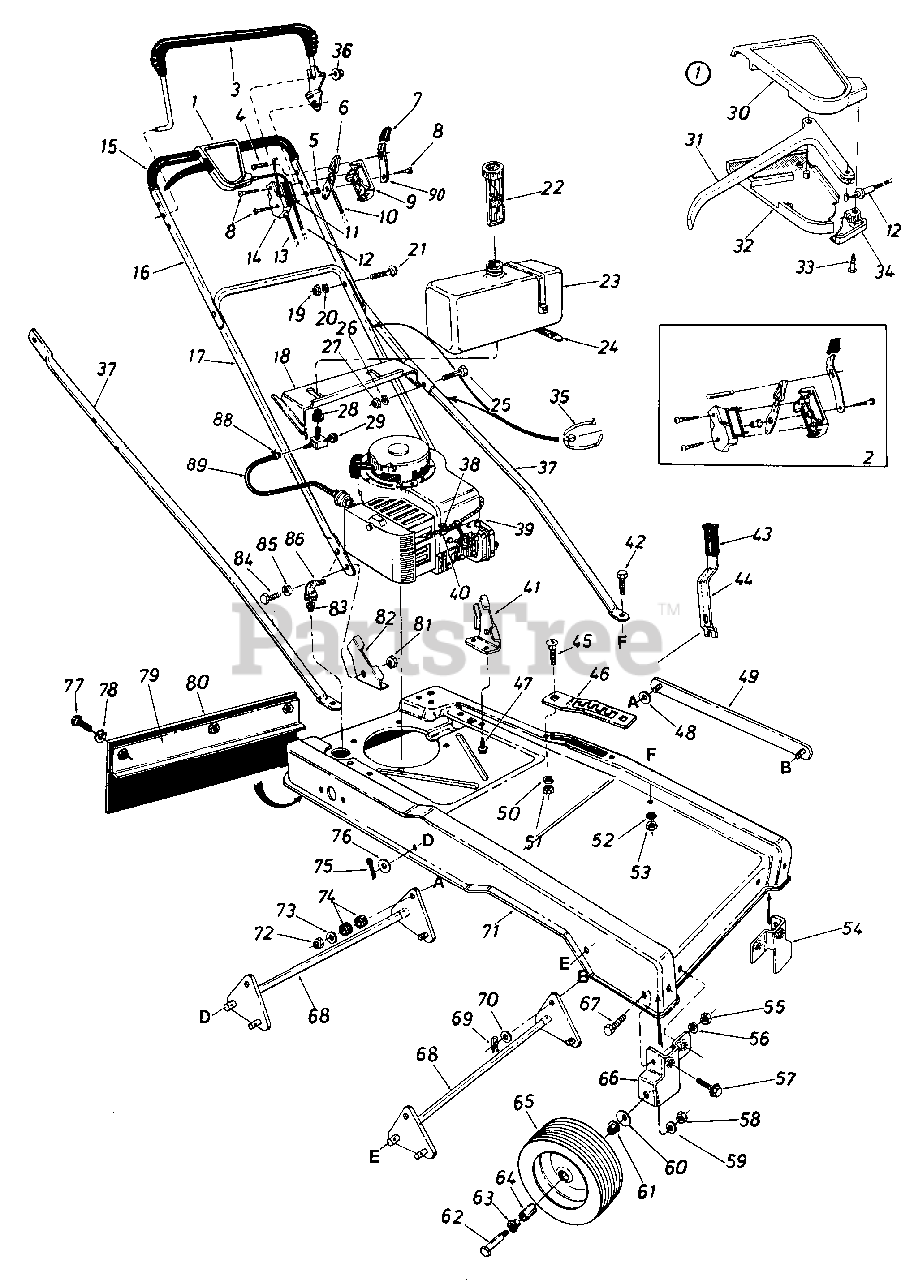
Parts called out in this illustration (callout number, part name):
1	WASHER-FL .322 ID x 1.25 x .060
2	KIT-THROTTLE CONTROL
4	PIN-LOCKING
5	PIN-CONTROL DISC
6	LEVER-THROTTLE CONT-REV
7	KNOB
8	SCREW-TRUSS MACH
9	PANEL HALF-CONTROL
10	WIRE-CONTROL
11	LABEL
12	CABLE-CLUTCH x 50.0
13	CABLE-CLUTCH
14	PANEL HALF-CLUTCH
15	GRIP-SHRINK-25 IN
16	HANDLE-UPPER
17	HANDLE-LOWER PAINTED
18	BRACKET-GAS TANK MTG
19	NUT-HEX 5/16-18
20	WASHER-LOCK-5/16
21	BOLT-CARRIAGE 5/16-18 x 1.50
22	GAUGE-GAS
24	TIE-CABLE
25	SCREW-HEX 5/16-24 x 1.25
26	WASHER-FL-.344ID x .75OD x .250 SP
26	WASHER-LOCK-5/16
27	NUT-5/16-24
28	BUSHING
29	VALVE-SHUT OFF
30	COVER-HALF-CONTROL
31	LEVER-CONTROL
32	COVER-HALF CONT-LWR
33	SCREW-FL C-SUNK AB
34	CAP-CABLE MTG
35	TIE-CABLE
37	STRUT-43.44 IN LG
38	SCREW-HEX WASH HD TAP
40	CLAMP-CASING
41	BRACKET-HANDLE MTG
42	SCREW-HEX 5/16-18 x .75
43	GRIP-FL BAR-END
44	HANDLE-LIFT
45	BOLT-CARRIAGE 5/16-18 x .62
46	BRACKET-SUPPORT
47	SCREW-HEX WASH HD 5/16-18X1/2
48	WASHER-FL-.406ID 1.25OD X.157/.172
49	WASHER-FL-.406ID 1.25OD X.157/.172
50	WASHER-LOCK-5/16
51	NUT-HEX 5/16-18
52	WASHER-LOCK-5/16
53	NUT-HEX 5/16-18
54	BRACKET ASSY-WHL-LH
55	NUT-HEX 5/16-18
56	WASHER-LOCK-5/16
57	SCREW-HEX SEMS 5/16-18 x .75
58	NUT-HEX CENTER L-3/8-16
59	WASHER-LOCK-3/8
60	WASHER-BELL .400 ID x .88 x .060
61	BEARING-FLANGE
62	SCREW-HEX 3/8-16 x 2.00
63	BEARING-BALL
65	BRACKET ASSY-WHL-RH
66	BRACKET ASSY-WHL-RH
67	SCREW-HEX SEMS 5/16-18 x .75
68	SHAFT ASSY-LIFT BRKT
69	PIN-INTERN COT-5/16 DIA
70	WASHER-FL-.385 ID x .87 OD x .06
71	FRAME-HI WHEEL
72	NUT-HEX INS L-3/8-24
73	WASHER-FL-.385 ID x .87 OD x .06
74	WASHER-RUBBER
75	PIN-COTTER-1/8 DIA x 1.00
76	WASHER-FL .510 x .995 x .060
77	SCREW-HEX 1/4-20 C .62
78	LOCK WASHER 1/4 DIA
79	STRIP ASSY RETAINING
81	NUT-HEX JAM 3/8-18
82	BRACKET-HANDLE MTG
84	SCREW-HEX 3/8-16 x .75
85	WASHER-LOCK-3/8
88	CLAMP-HOSE
90	SPRING-LOCKOUT
